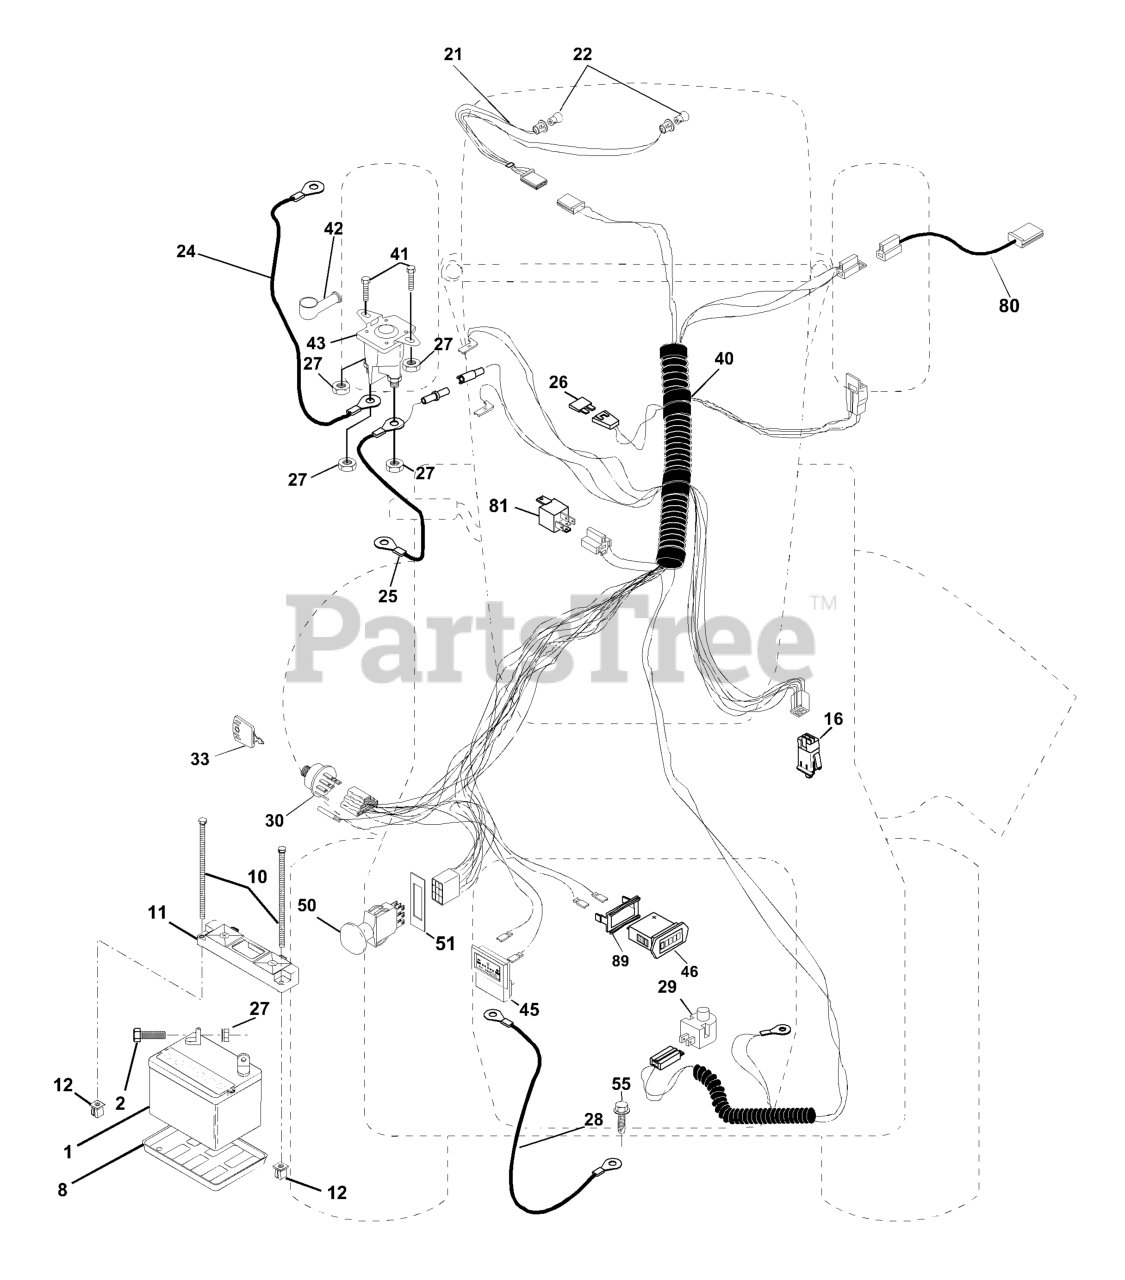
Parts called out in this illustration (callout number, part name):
1	BATTERY 12V .35 AMP
2	BOLT.HEX.1/4.X.3/4.DICHROMATE
8	BATTERY TRAY T
10	BOLT 1/4-20 X 7.5
11	BATTERY HOLDDOWN FRONT MOUNT
12	NUT, PUSH NYLON 1/4" BATTERY
16	SWITCH INTERLOCK
24	BATTERY CABLE GT
25	CABLE BATTERY 6 GA 22" W/16W
26	FUSE 15 AMP
27	NUT
28	CABLE GROUND 6 GA 21" 90T BLK
29	PLUNGER SWITCH (COLOR:OLIVE)
30	SWITCH IGN
33	KEY MLD GEN DELTA
40	HARNESS IGN.
41	BOLT
42	TERMINAL COVER
43	SOLINOID
46	HOUR METER
50	PTO SWITCH
51	FRAME RETAINING RING
55	Screw, Thdrol 5/16-18 x 1/2 TYT
80	HARNESS, CLUTCH
81	RELAY.ASSY.T
89	BRACKET SNAP-IN HOURMETER
